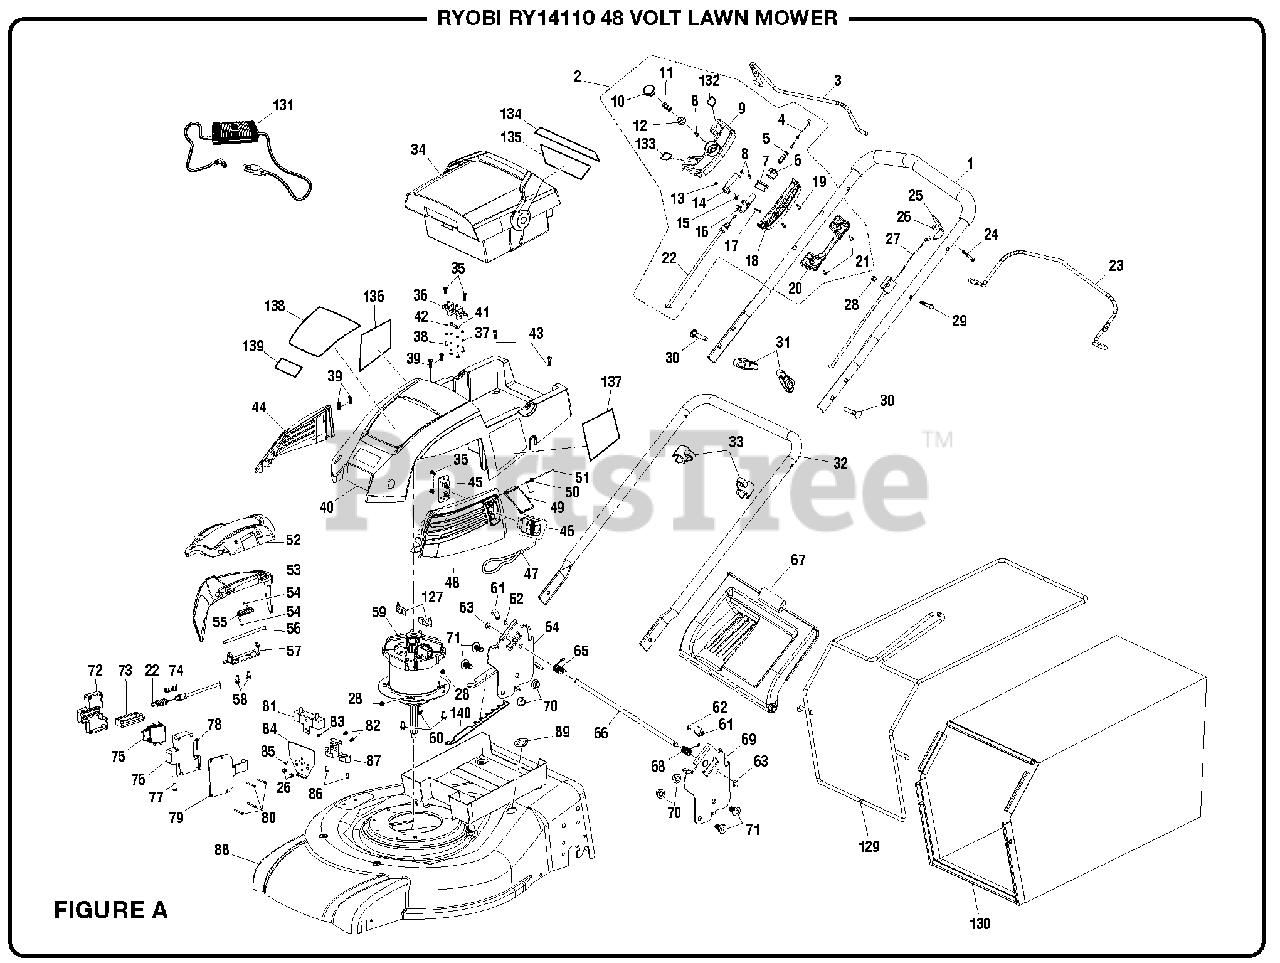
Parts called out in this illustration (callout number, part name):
1	Upper Handle Assembly
2	Start Cable Assembly
3	Start Bail
4	Start Cable (Short)
5	Compression Spring
8	Screw (M2.9 x 8 mm, Pan Hd.)
9	Upper Cover Motor Engagement Box
10	Push Button
12	Bottom Button
14	Spring Plate
15	Torsion Spring
16	Steel Slide
17	Bolt (M3 x 20 mm)
18	Motor Engagement Box Lower Cover
19	Screw (M3.5 x 20 mm, Pan Hd.)
20	Motor Engagement Box Lower
21	Screw (M4.2 x 20 mm, Pan Hd.)
22	Start Cable (Long)
23	Drive Bail
24	Bolt (M5 x 30 mm)
25	Stop Block
26	Lock Nut (M5)
27	Drive Cable
28	Lock Nut (M6)
29	Bolt (M6 x 35 mm, Hex Hd.)
30	Screw (M8 x 48 mm, Handle)
31	Handle Knob
32	Lower Handle
33	Cord Retainer
34	Battery Assembly (See Figure B)
35	Screw (M3.5 x 12 mm, Pan Hd.)
36	Lower Connector
37	Lock Washer (M5)
38	Screw (M5 x 6 mm)
39	Screw (M5 x 12 mm)
40	Motor Shroud
41	Copper Plate
42	Washer (M5)
43	Screw (M5 x 8 mm)
44	Vent (Left)
45	Fuse Lower Connector
46	Fuse Key Assembly (Inc. Key No.47)
48	Vent (Right)
49	Fuse Key Cover
50	Fuse Key Spring
51	Fuse Key Hinge Rod
52	Side Discharge Door
53	Side Discharge Deflector
54	Spring End Cap
55	Door Spring
56	Door Hinge Rod
57	Hinge Bracket
58	Bolt (M6 x 8 mm, Hex Hd.)
60	Bolt (M6 x 12 mm, Hex Hd.)
61	Mounting Bracket
62	Retaining Ring (6)
63	Retaining Ring (8)
64	Handle Bracket (Right)
65	Torsion Spring (Right)
66	Rear Cover Rod
67	Rear Cover
68	Torsion Spring (Left)
69	Handle Bracket (Left)
70	Lock Nut (M10)
71	Bolt (Button Hd.)
72	Motor Switch Cover (Outside)
73	Motor Switch Actuator
74	Compression Spring
76	Motor Switch Cover (Inside)
77	Screw (M6.3 x 16 mm, Pan Hd.)
78	Screw (M5 x 40 mm, Pan Hd.)
79	Motor Switch Mounting Bracket
80	Screw (M4.2 x 35 mm, Pan Hd.)
82	Screw (M5 x 20 mm, Pan Hd.)
83	Lock Nut (M4)
84	Heat Shield
85	Screw (M4 x 12 mm, Pan Hd.)
86	Screw (M4.8 x 12 mm, Pan Hd.)
87	Resistance Support
127	Brush Assembly
131	Charger
132	Ignition Instruction Label 1
133	Ignition Instruction Label 2
134	Battery Status Label
135	Battery Warning Label
136	Danger Label 1
137	Danger Label 2
138	Main Label
139	Ryobi Badge
140	Height Adjust Label
